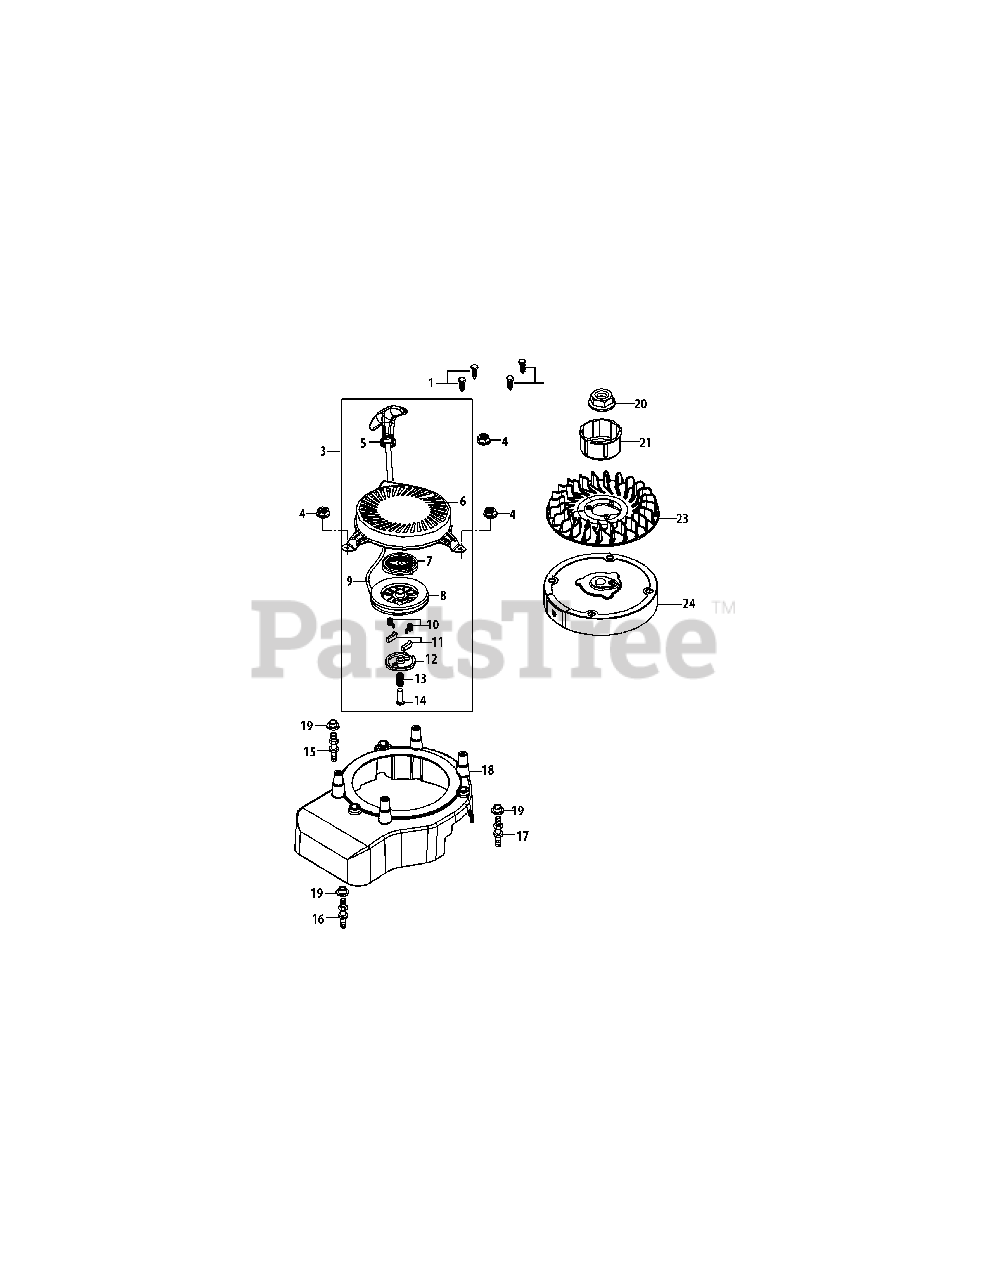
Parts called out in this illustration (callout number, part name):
1	Self-Tapping Bolt, Hilo #12-16 X 1.00"
3	Recoil Starter Assembly
4	Nut M6 X 10 Mm
5	Starter Handle
6	Starter Housing Weldment
7	Recoil Spring
8	Starter Pulley
9	Starter Rope
10	Starter Pawl Return Spring
11	Starter Pawl
12	Pressure Plate
13	Pressure Plate Spring
14	Pressure Plate Bolt
15	Starter / Shroud Stud M6×85-48
16	Starter / Shroud Stud M6×87-51.5
17	Starter / Shroud Stud M6×79
18	Inner Shroud
20	Nut M14×1.5
21	Starter Cup
23	Cooling Fan
